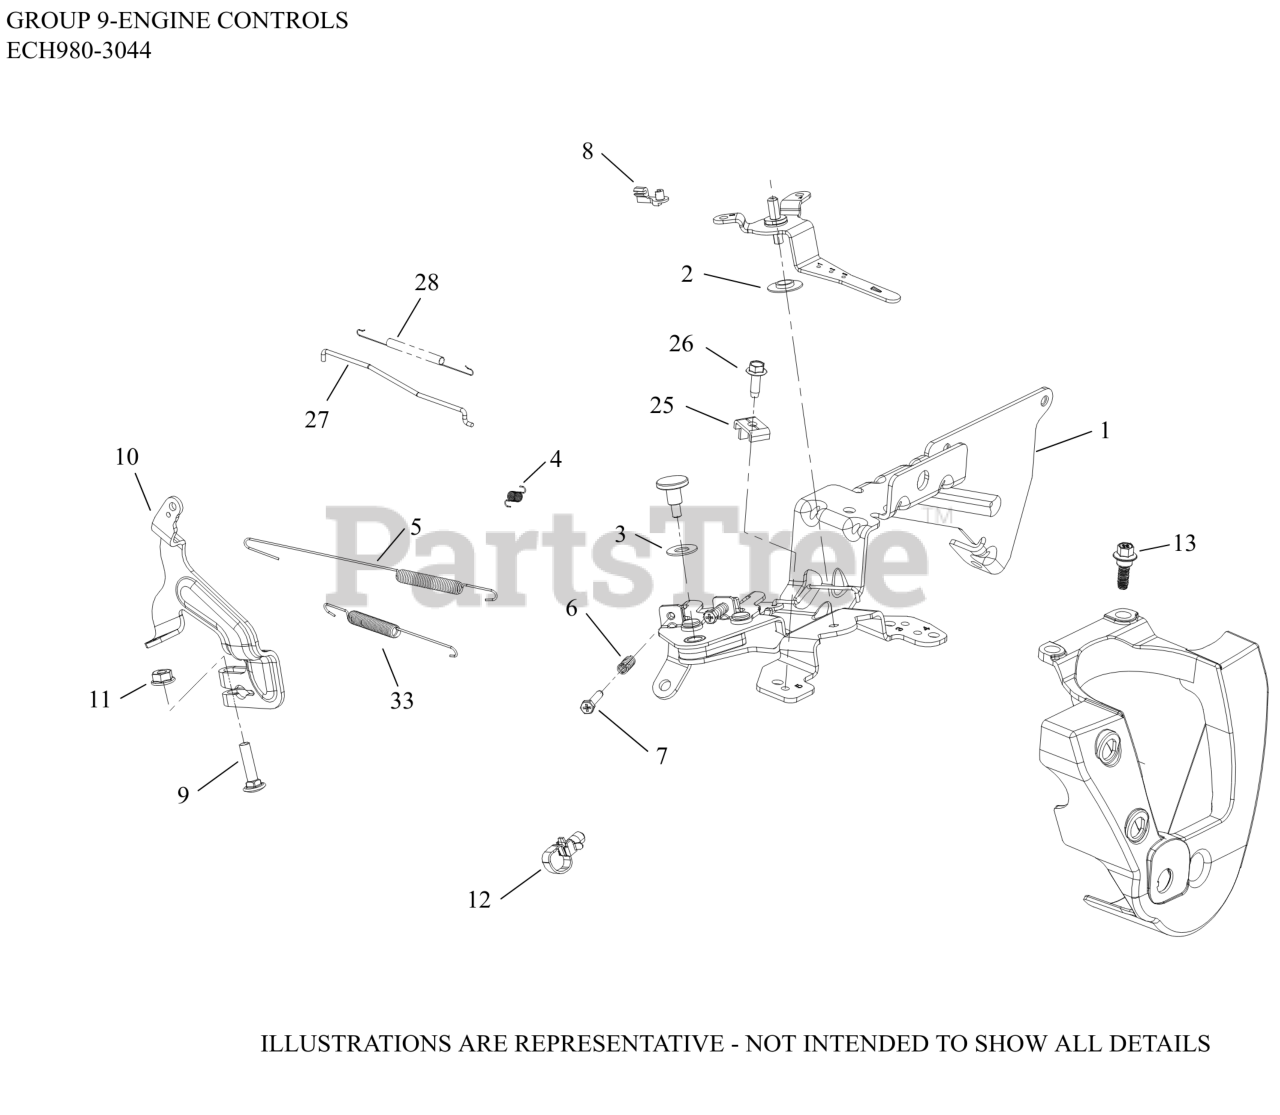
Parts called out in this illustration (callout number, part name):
1	CONTROL ASSEMBLY, SPEED (H/S EFI)
2	WASHER, NYLON SHOULDER
3	WASHER, FLAT 9 MM
4	SPRING, RETURN
5	SPRING, GOV (HORZ IDLE 1626-1800)
5	SPRING, GOVERNOR, HIGH SPEED
6	SPRING, SPEED CONTROL (SHORT)
7	SCREW, PHL THD FRM M4X0.7X25
8	BUSHING, THROTTLE LINKAGE
9	BOLT, RD HD SQ NECK M6X1.0X25
10	KIT, GOVERNOR LEVER
11	NUT, FLG M6X1.0
12	TIE, WIRE
25	CLAMP, CABLE CABLE
26	SCREW, THREAD FORMING
27	LINKAGE, THROTTLE
28	SPRING, LINKAGE
34	LINKAGE, CONTROL LEVER
